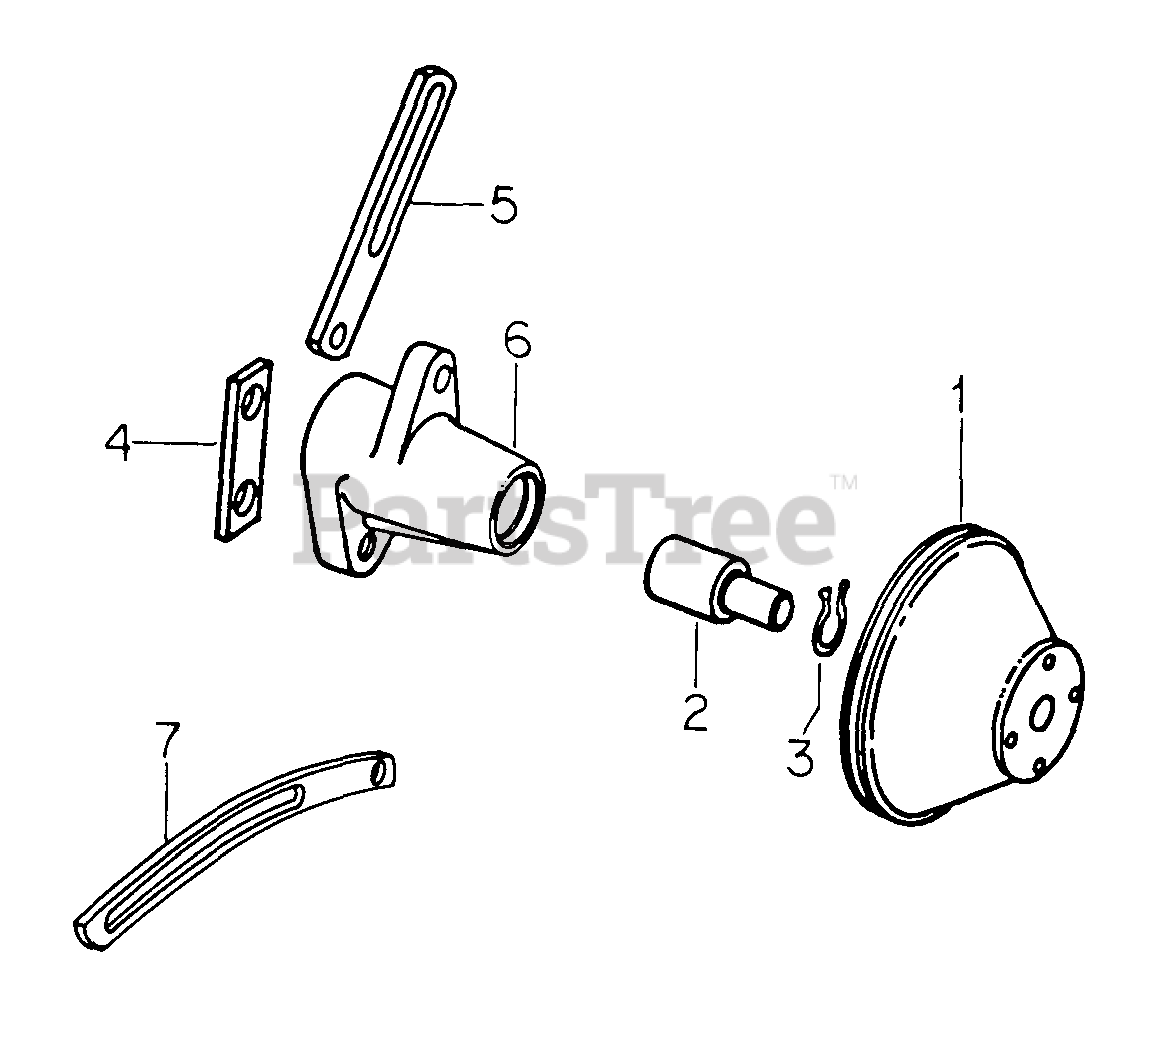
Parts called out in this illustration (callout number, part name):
1	PULLEY, FAN
2	SHAFT AND BEARING ASSY
3	RETAINER, BEARING
4	BAR, ADAPTER
5	BRACE, MOTOR-GENERATOR
6	BRACKET, FAN PULLEY MOUNTING
7	BRACE, ALTERNATOR-GENERATOR
